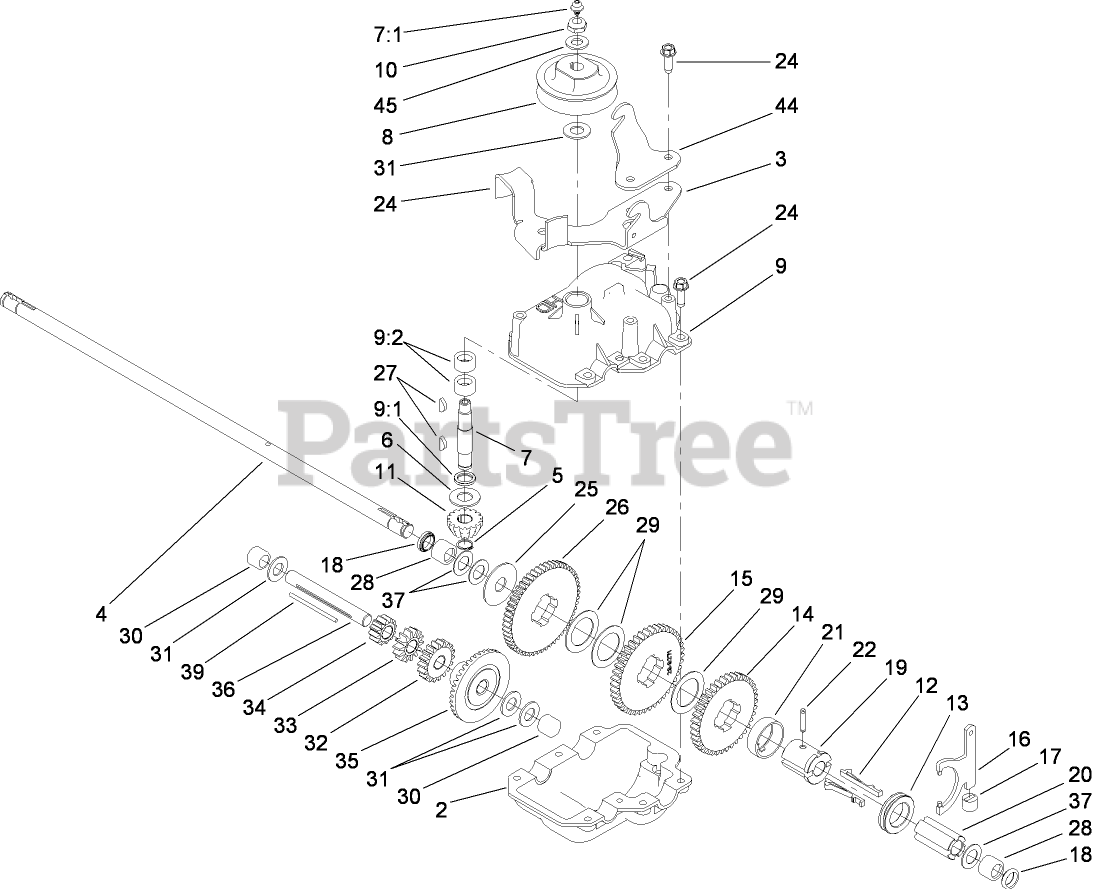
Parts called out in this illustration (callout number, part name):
3	BRACKET-GUIDE, BELT
4	SHAFT-OUTPUT
5	RING-RETAINING
6	WASHER-THRUST
7	INPUT SHAFT ASM
7:1	FITTING-GREASE, ZERK
8	PULLEY
9	UPPER GEARCASE ASM
9:2	BEARING-NEEDLE
10	NUT-HEX
11	PINION-BEVEL
12	KEY-SHIFT
13	COLLAR-SHIFT
14	GEAR-38T
15	GEAR-42T
16	YOKE-SHIFT
17	BUSHING-YOKE
18	SEAL-OIL
19	SLEEVE-GEAR
20	SLEEVE
21	RETAINER-KEY
22	PIN-GROOVE
24	SCREW-HWHTF
25	WASHER
27	KEY-WOODRUFF
29	WASHER
30	BEARING-NEEDLE, CLOSED
31	WASHER-THRUST
32	GEAR-18T
33	GEAR-14T
34	GEAR-12T
35	GEAR-BEVEL
36	SHAFT-INTERMEDIATE
37	WASHER-PLAIN
44	BRACKET-ENGAGE, TRACTION
45	WASHER-FLAT
